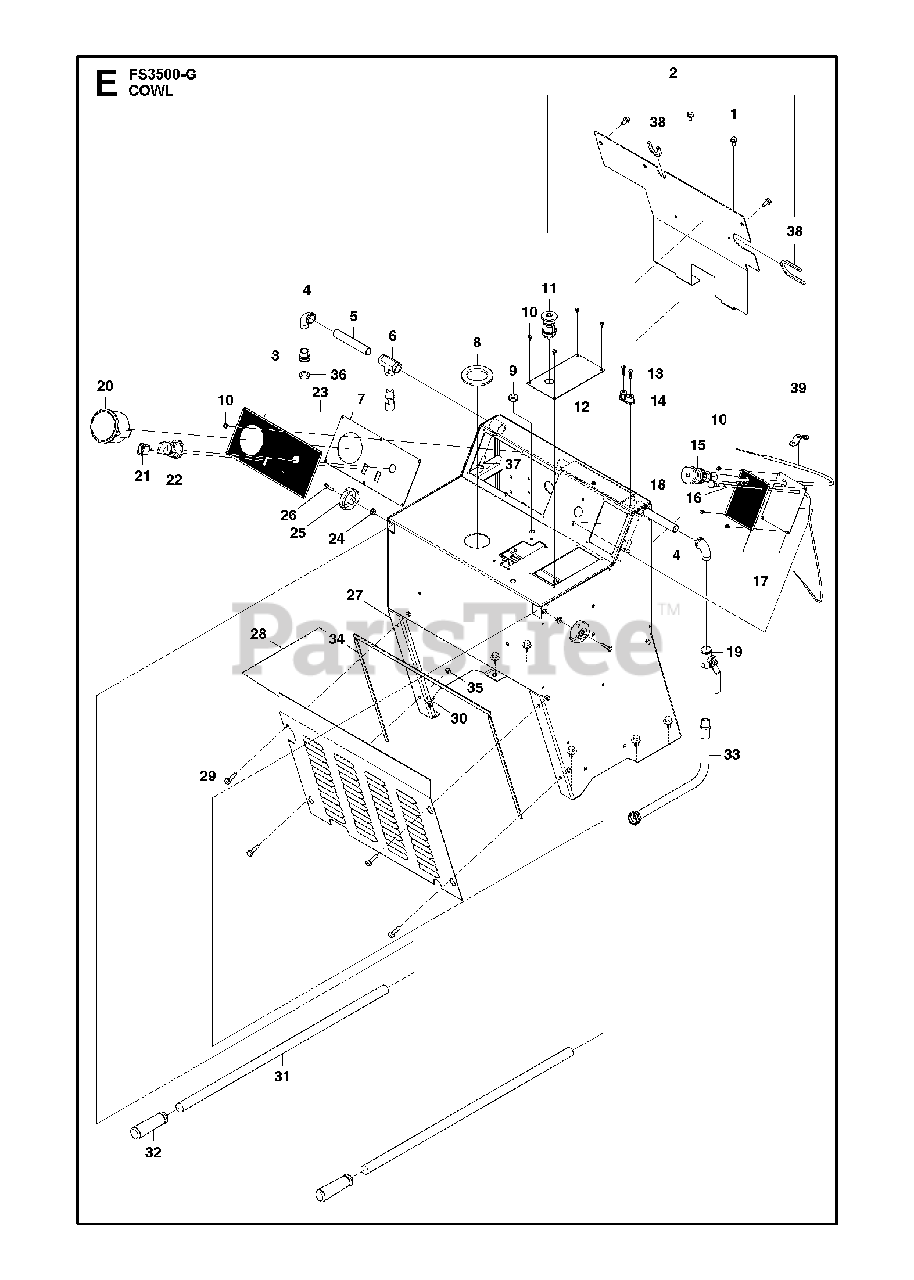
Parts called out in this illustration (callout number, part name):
24	TURNING KNOB
25	HEXAGON NUT FLANGE
35	HEXAGON LOCKING NUT
